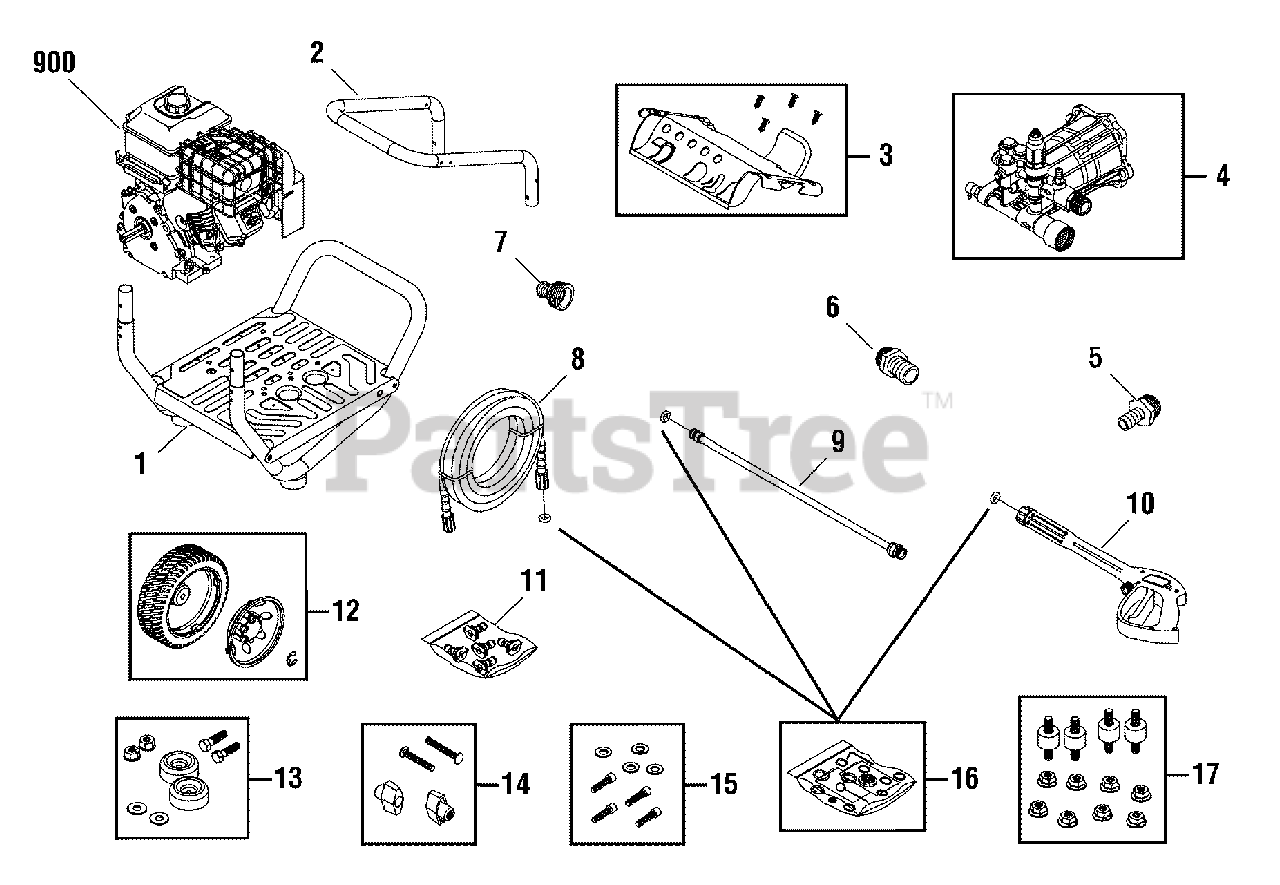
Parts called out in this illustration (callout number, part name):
8	HOSE
9	EXTENSION, QC
10	GUN
11	KIT, QC Nozzles
13	MOUNT, Vibration
14	KIT, Hardware, Handle
15	KIT, Hardware, Pump Mounting
16	KIT, 0-Ring
17	KIT, Vibration Mount
900	* ENGINE
